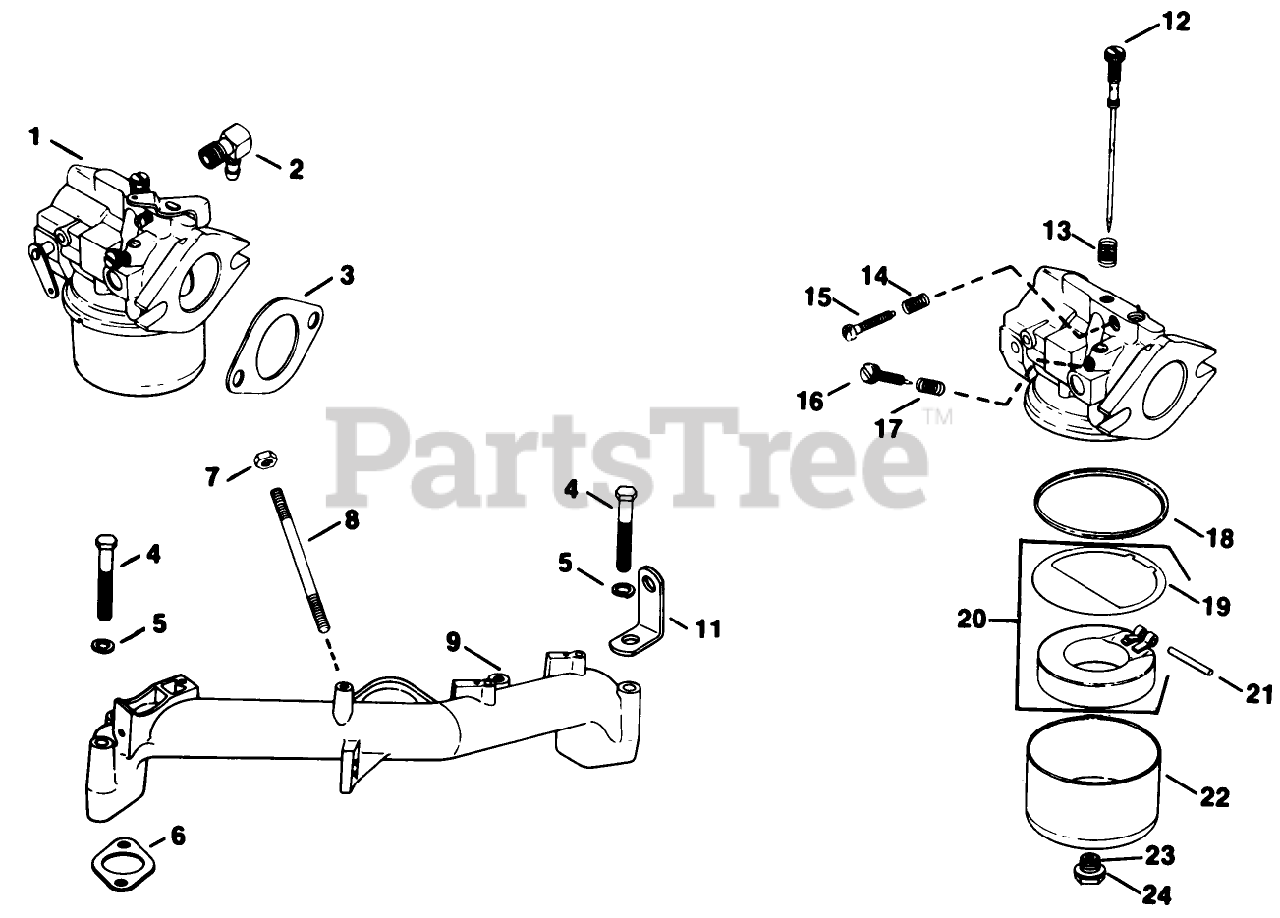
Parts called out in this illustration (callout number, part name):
1	Carburetor Assembly
2	Connector-90deg.
3	Gasket
4	Screw-H.C.
5	Washer
6	Gasket-Intake
7	Nut
8	Stud
9	Manifold-Intake
11	Strap-Lifting
12	Needle-Main Fuel Adj.
13	Spring-Main
14	Spring-Idle Speed
15	Screw
16	Needle-Idle Adj.
17	Spring-Idle
18	Gasket-Bowl
19	Gasket-Bowl Baffle
20	Kit-Float
21	Pin-Float Hinge
22	Bowl
23	Screw-Bowl Retainer
24	Gasket-Bowl Screw
